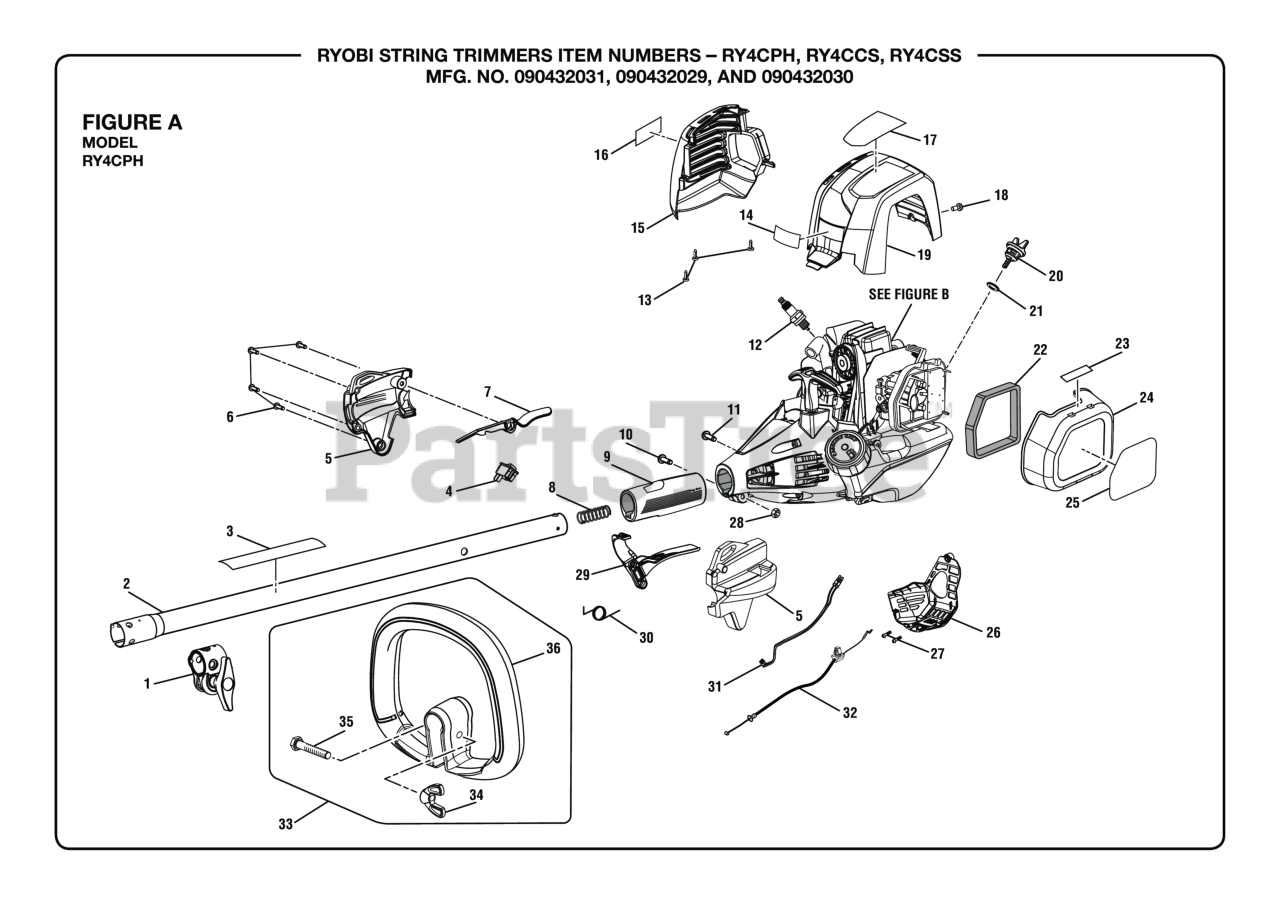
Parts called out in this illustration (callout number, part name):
1	Boom Clamp Assembly
2	Upper Boom Assembly
3	Warning Icon Label
4	Stop Switch (Momentary Contact)
5	Control Handle Assembly (Inc. Key No. 6)
6	Screw (M4 x 20 mm, T20 Torx Pan Hd. S.T.)
7	Trigger Lock
8	COMPRESSION SPRING
9	Rear Handle Grip
10	Screw (M6 x 20 mm, T27 Torx Button Hd.)
11	Screw (M4 x 8 mm, T25 Torx Pan Hd. T.F.)
12	Spark Plug (Champion RY4C)
13	Screw (M4 x 12 mm, T20 Torx Truss Hd.)
14	Logo Label
15	Muffler Housing (Inc. Key No. 16)
16	Warning Label (Combustion)
17	X430 Label (RY34006)
18	Shoulder Screw (M4 x 11 mm, T25 Torx Pan Hd.)
19	Top Cover
20	Oil Cap/Dipstick (Incl. key no. 12)
22	Air Filter
23	Choke Label
24	Air Filter Cover
25	Starting Label
26	CE Cover (Bottom Cover)
27	Screw (#6-19 x 1/2 in., Phillips Hd. T.F.)
28	Hex Nut (M6.3 x 1)
29	Throttle Trigger
30	Torsion Spring (Throttle Trigger)
31	Lead Assembly
32	Throttle Cable
33	Front Handle Assembly
34	Wing Nut (1/4-20, Plastic)
35	Screw (1/4-20 x 40 mm, Cap Hex Hd.)
36	Front Handle
